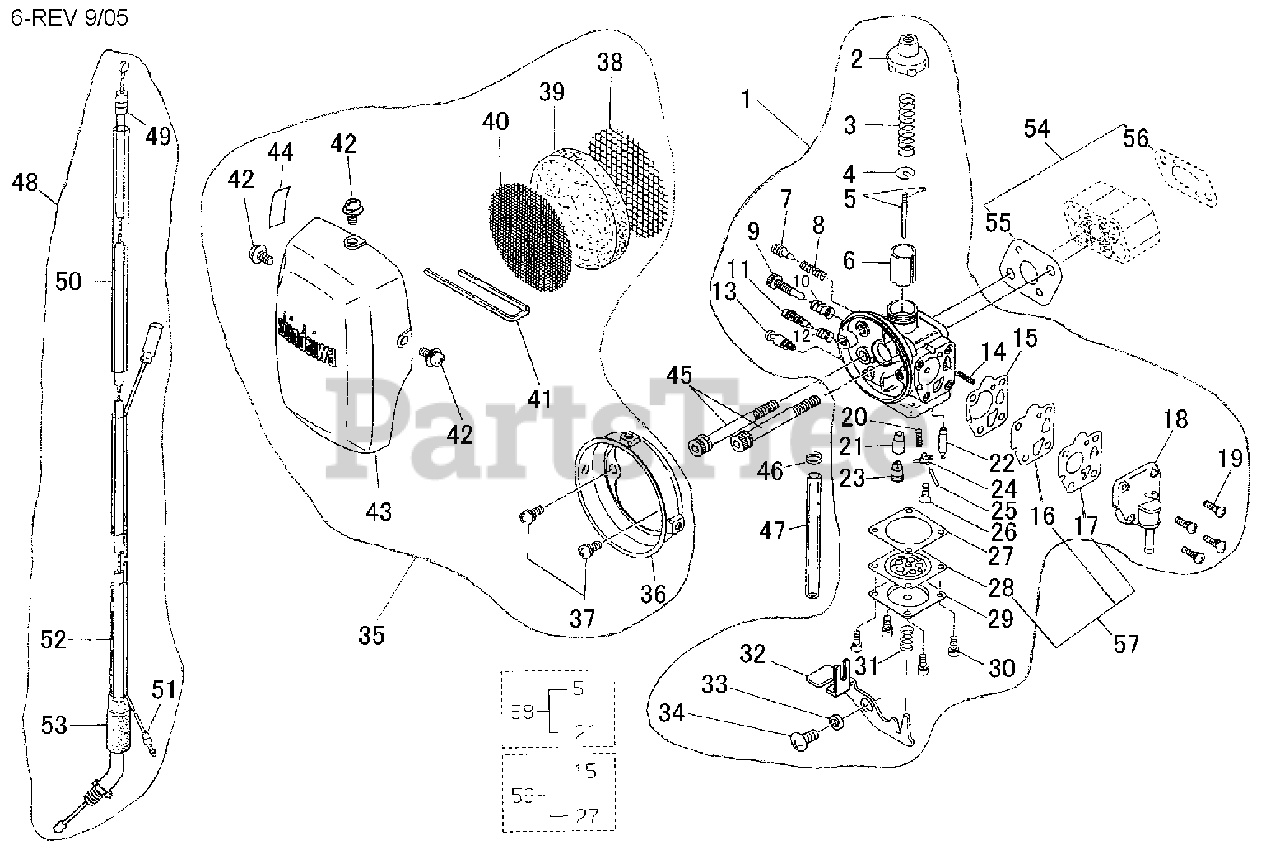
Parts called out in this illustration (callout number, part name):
1	CARBURETOR
2	CAP
3	SPRING
4	RETAINER
5	NEEDLE
6	VALVE, THROTTLE
7	SCREW, SLOW AIR
8	SPRING
9	SCREW, IDLE ADJUST
10	SPRING
11	SCREW, IDLE ADJUST
12	SCREW, IDLE ADJUST
13	VALVE, OVERFLOW
14	SPRING
15	GASKET, METERING
16	DIAPHRAGM, METERING
17	VALVE, PUMP
18	BODY, PUMP
19	SCREW
20	SPRING
21	JET
22	VALVE, INLET NEEDLE
23	HOLDER, JET
24	LEVER, METERING
25	PIN, METERING LEVER
26	SCREW, METERING LEVER PIN
27	GASKET
28	DIAPHRAGM, METERING
29	COVER, DIAPHRAGM
30	SCREW
31	SPRING
32	LEVER, TICKLER
33	COLLAR
34	SCREW
35	AIR CLEANER ASSY
36	CASE, AIR FILTER
37	SCREW
38	SCREEN - INNER
39	FILTER, AIR - FOAM
40	SCREEN - OUTER
41	CLIP
42	SCREW
43	COVER, AIR FILTER
44	LABEL - CHOKE
45	SCREW - 5X50
46	RING, RETAINING - 6
47	PIPE
48	CONTROL CABLE ASSY
49	CABLE, THROTTLE
50	TUBE, PROTECTIVE
51	LEAD
52	TUBE, PROTECTIVE
53	CAP, DUST
54	GASKET SET
55	GASKET
56	GASKET
57	DIAPHRAGM KIT
58	JET NEEDLE KIT
59	GASKET KIT
